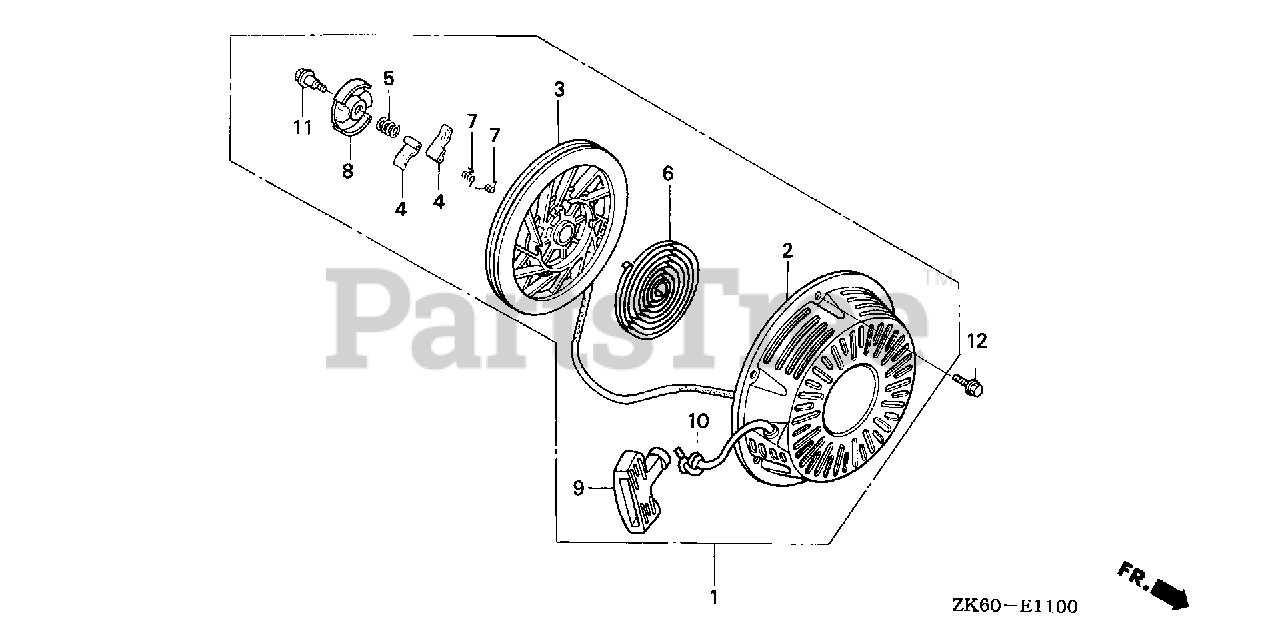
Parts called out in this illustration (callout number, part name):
1	STARTER ASSY., RECOIL *NH1* (BLACK)
1	STARTER ASSY., RECOIL *T34* (SIMPSON BLUE)
1	STARTER ASSY., RECOIL *R280* (POWER RED)
2	CASE, RECOIL STARTER *NH1* (BLACK)
2	CASE, RECOIL STARTER *T34* (SIMPSON BLUE)
2	CASE, RECOIL STARTER *R280* (POWER RED)
3	PULLEY, RECOIL STARTER
4	RATCHET, STARTER
5	SPRING, FRICTION
6	SPRING, STARTER RETURN
7	SPRING, RATCHET
8	RETAINER, SPRING
9	GRIP, STARTER
10	ROPE, RECOIL STARTER
11	SCREW, CENTER
12	BOLT, FLANGE (6X10)
